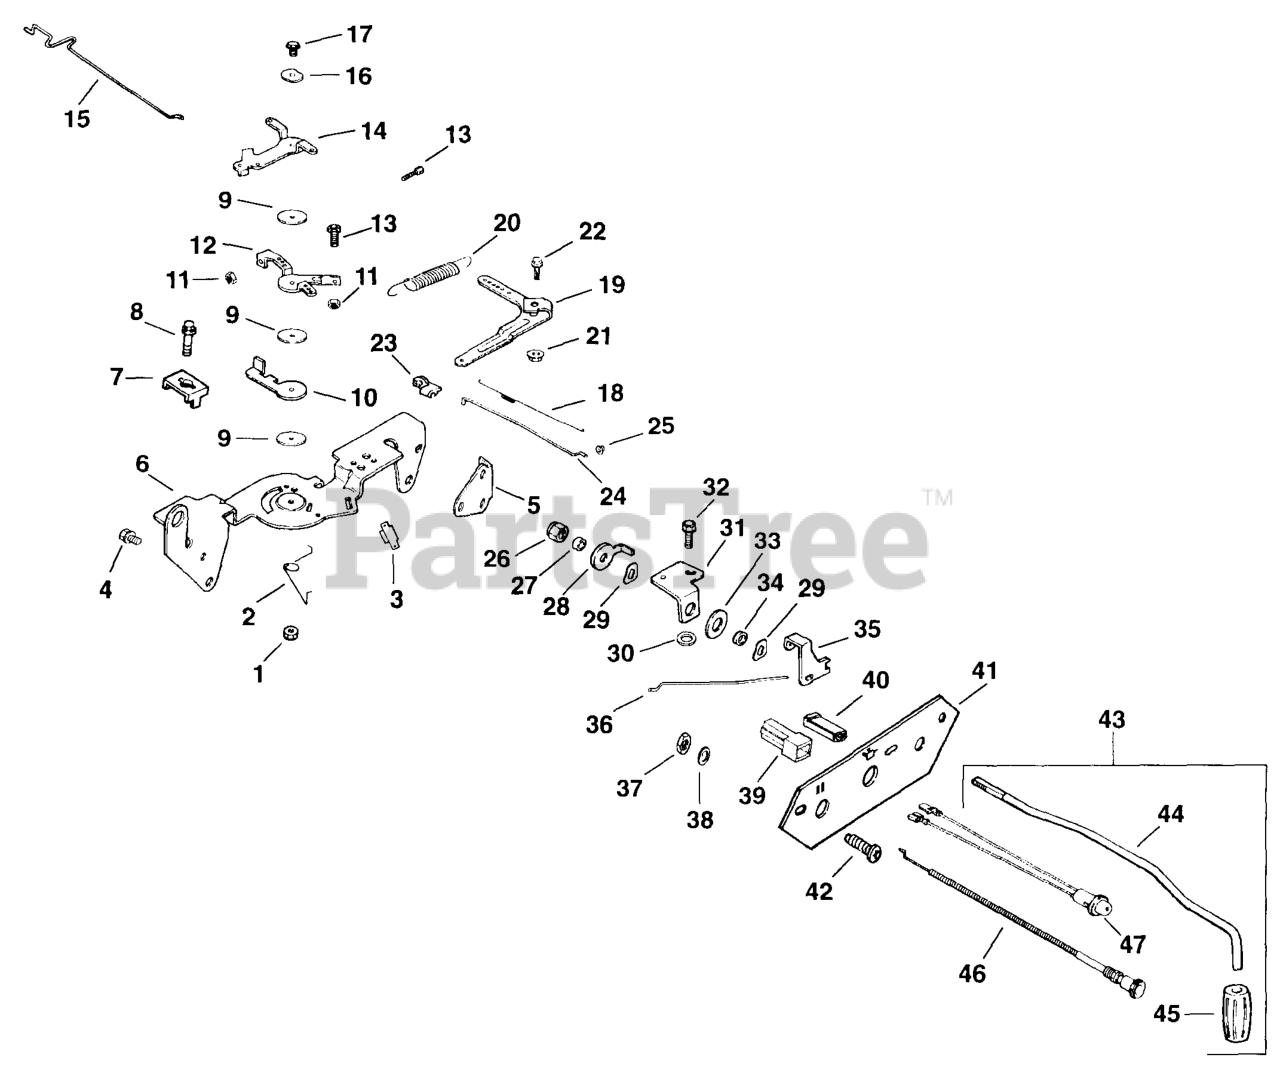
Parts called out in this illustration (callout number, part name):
1	Nut, Hex. Flange M5x0.8
2	Spring, Choke Return
4	Screw, Hex. Flange M6x1.0x16
6	Bracket, Control
7	Clamp, Cable
8	Screw, Hex. Flange M5x0.8x16
9	Washer, Plain 5 Mm
10	Lever, Throttle Actuator
11	Nut, Hex. Flange M4x0.7
12	Lever, Throttle Control
13	Screw, Hex. Cap M4x0.7x30
14	Lever, Choke
15	Linkage, Choke
16	Washer, Wave
17	Screw, Hex. Flange M5x0.8x20
18	Spring, Linkage
19	Lever, Governor
20	Spring, Governor
21	Nut, Hex. Flange M6x1.0
22	Screw, Hex. Cap M6x1.0x25
23	Bushing, Linkage - Black
24	Linkage, Throttle
25	Bushing, Linkage - Natural
